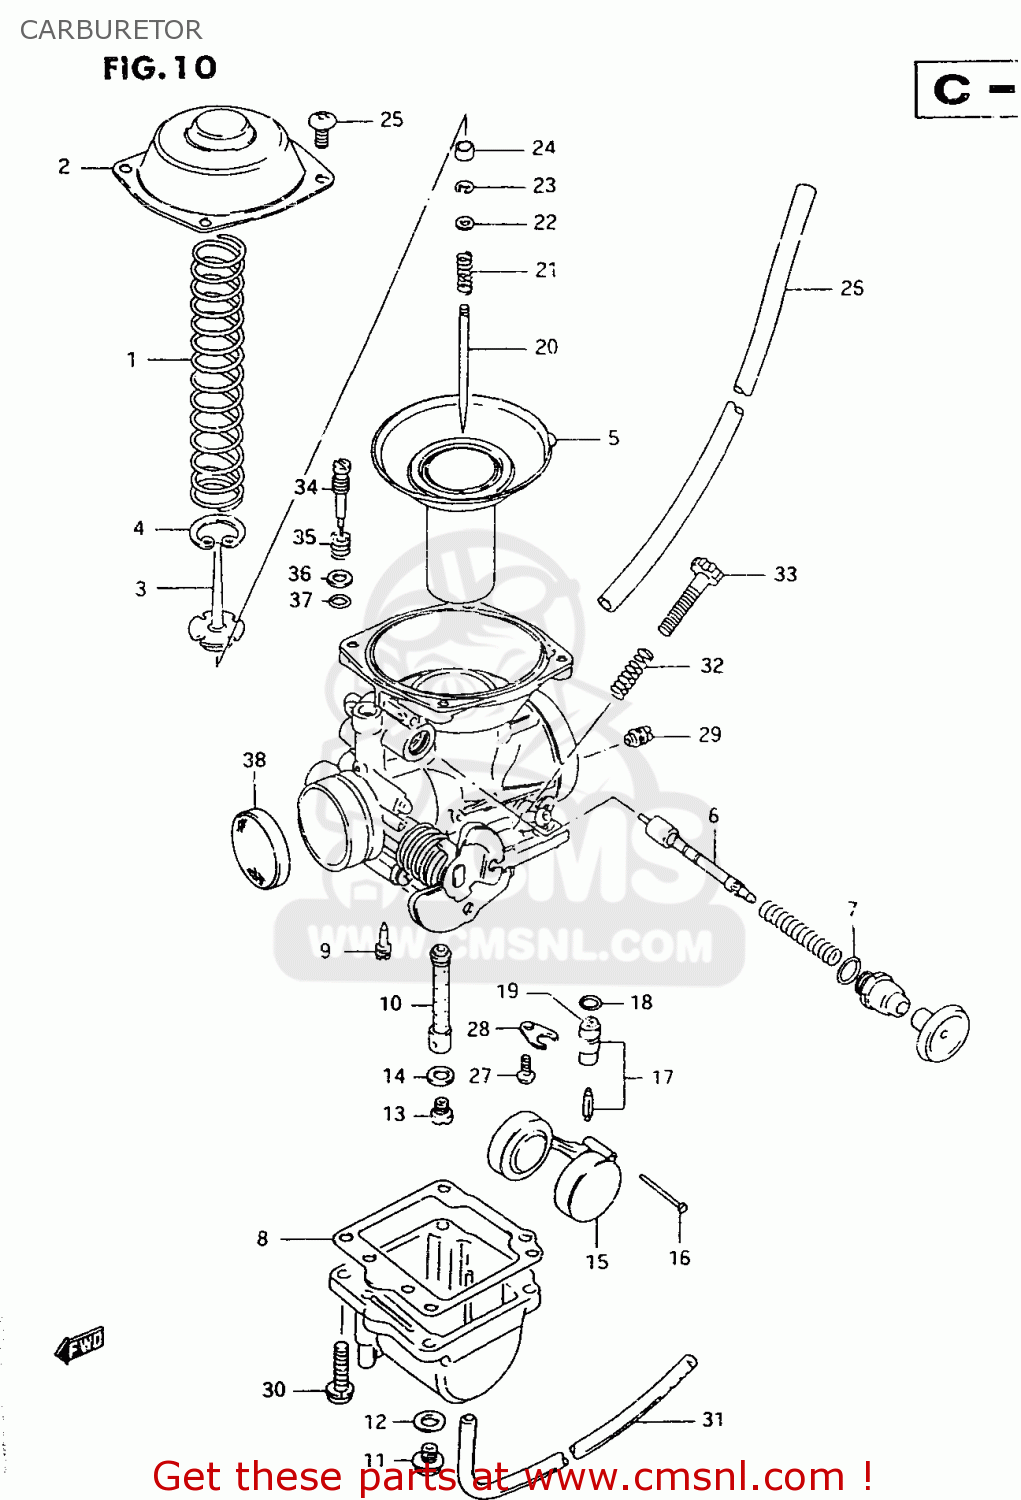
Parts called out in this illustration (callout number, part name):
1	SPRING
2	COVER
3	HOLDER,GUIDE
4	E RING
5	DIAPHRAGM ASSY
6	PLUNGER ASSY
7	O RING
8	GASKET,FLOAT CAHMBER (NAS)
9	JET,PILOT(42.5)
10	JET,NEEDLE(P-1)
11	PLUG,DRAIN
12	GASKET (NAS)
13	JET,MAIN(130)
14	WASHER,NEEDLE NOZZLE
15	FLOAT
16	PIN,FLOAT
17	VALVE ASSEMBLY,NEEDLE
18	O-RING,NEEDLE VALVE
19	FILTER
20	NEEDLE,JET
21	SPRING
22	WASHER
23	CLIP
24	RING
25	SCREW
26	HOSE (5X8X325)
27	SCREW 4X6
28	PLATE
29	JET,AIR(150)
30	SCREW
31	HOSE,3.5X6.5X2
32	SPRING
33	ADJUSTER
34	SCREW,PILOT AIR
35	SPRING
36	WASHER
37	O RING,PILOT AIR SCREW
38	FILTER
